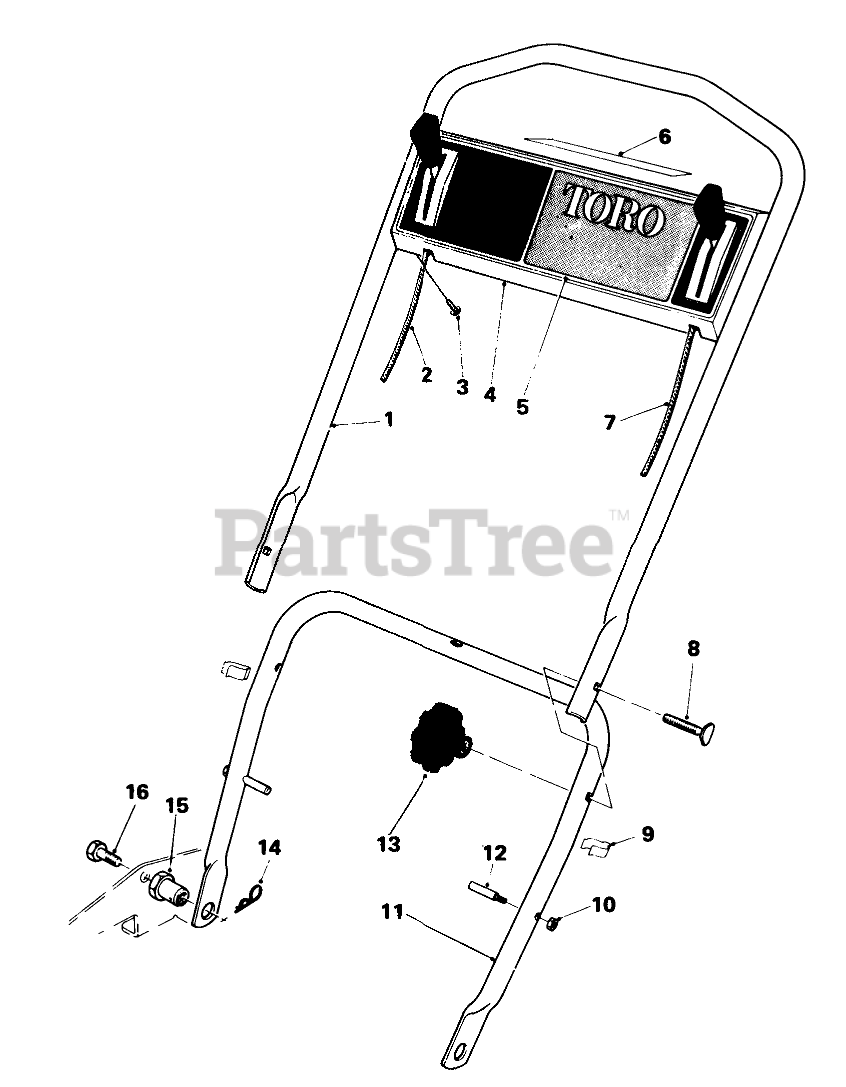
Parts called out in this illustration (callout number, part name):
1	UPPER HANDLE
2	Throttle Control
3	SCREW-HWHTF
4	Control Plate (Incl. Ref. #5)
5	Decal-Control Plate
6	Decal-Instruction
7	Traction Control
8	SCREW-HANDLE
9	BOWDEN CLIP
10	Nut
11	LOWER HANDLE
12	HANDLE PIN
14	PIN-COTTER, HAIR
15	HANDLE PIVOT NUT
16	SCREW-HH
